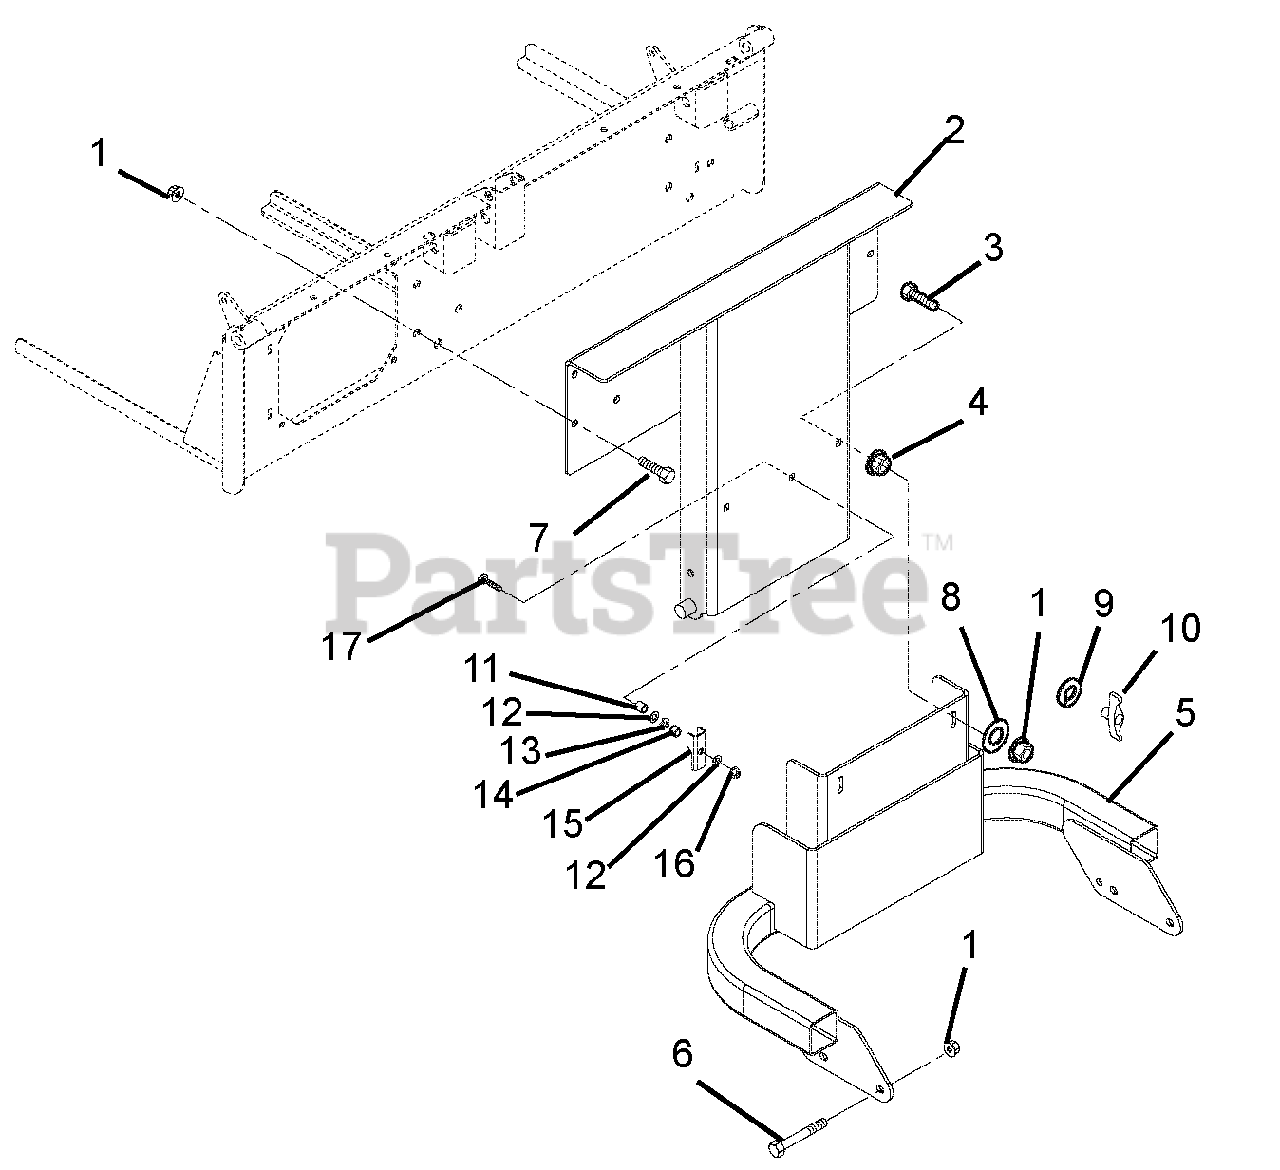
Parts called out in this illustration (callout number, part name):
1	Nut, .38-16 Nyloc Flange
2	Upper Mount, 2-Bag
3	Bolt, Round Head Square Neck .38-16 x 1.75 Grade 5
4	Nut, Spinlock Flange .375
5	Mount, Bagger 100 Series
6	Bolt, Hex .38-16 x 2.50 Grade 5
7	Bolt, Hex .38-16 x 1.00 Grade 5
8	Washer, Flat Steel .406 x 1.50 x .245
9	Washer, Locking .375 x .115 Heavy (Tool-less hardware option)
10	Nut, Wing .38-16 (Tool-less hardware option)
11	Spacer .41 x .75 x .88
12	Washer, Flat Steel .438 x 1.00 x .083
13	Wave Washer .640 x .875 x .125 Free Height
14	Bushing, Sleeve .377 x .624 x .235
15	Latch, Bagger Upper Mount
16	Nut, Locking Top Flange .38-16
17	Bolt, Round Head Square Neck .38-16 x 2.00 Grade 5
